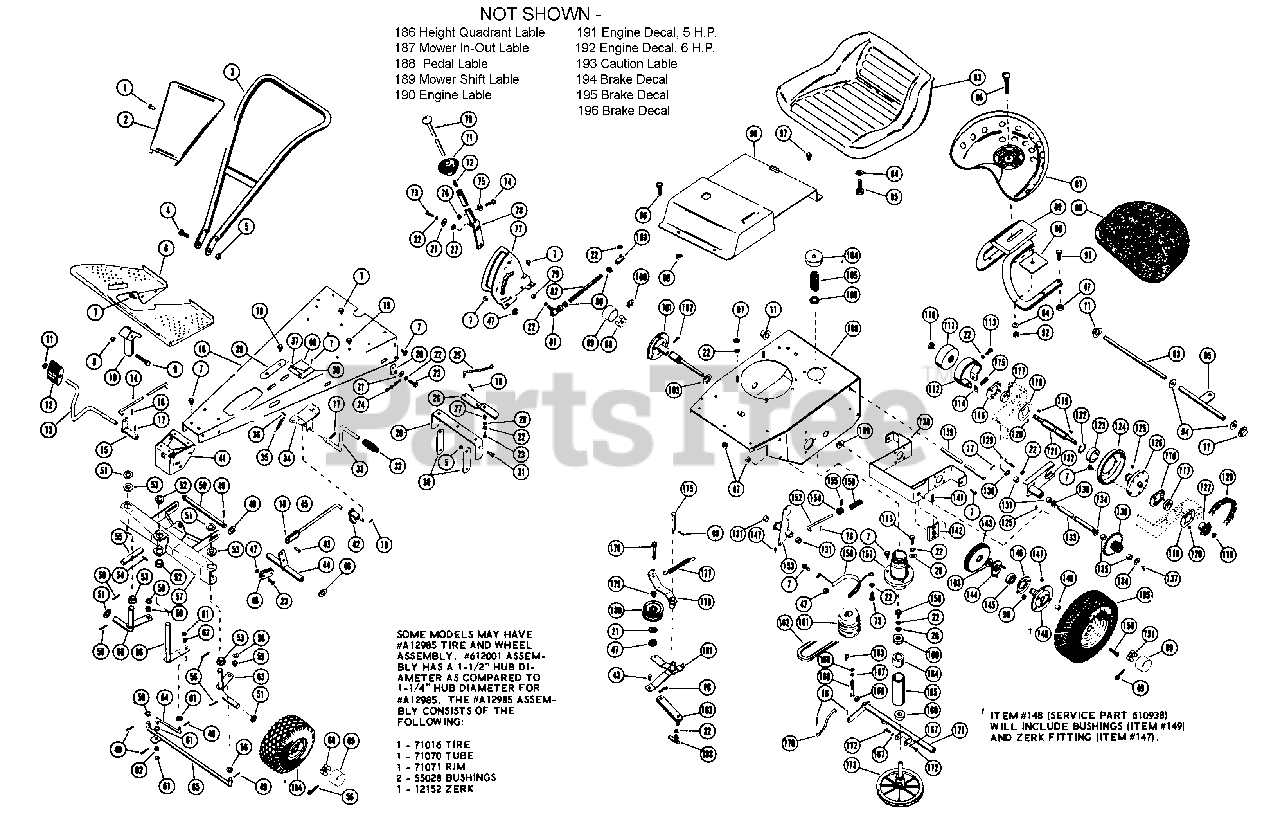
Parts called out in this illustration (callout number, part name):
1	RVT-POP.125 X .294 DOME
3	HANDLE BAR
4	BLT-HEX .38-16X2.50 PL GR2
5	NUT-LK-CTR .375-16 GR A PL
6	FOOT REST
7	BLT-SERHFWH .31-18X.50 PL
8	NUT-LK-CTR .250-20 PL
9	BLT-HEX .25-20X1.50
10	STEER BLOCK
11	CAP, .50 ROD YWZC
14	FRONT CLTCH ROD
16	PIN-COTR .09X.75 PL
17	PIN-ROLL .188X1.00
18	FRAME CHANNEL
19	BLT-SCRHFWH .38-16X.50 PL
20	BLADE BRAKE
21	WSHR-FL-STL .38X.875X.083 PL
22	WSHR-LK .312X.097 PL HVY
23	BLT-HEX .31-18X.75 PL GR2
24	BRAKE RELEASE CHAIN
26	CLTCH TRANSFER LEVER
27	SPACER BUSHING .5 X .32 X .21
28	WSHR-FL-STL 1.062X2.500X.165YZ
29	HANGER BRACKET
30	HANGER LINK
31	SHOULDER BOLT
33	MOWER CLTCH PEDAL
34	MOWER CLUTCH BRACKET
35	SG-TENS ??X.25X1.31 WLD 12 `
36	PIN-GRV .188X.75 TP G
38	THROTTLE CONTROL
39	GUIDE PLATE
40	BRAND PLATES
41	FRONT FRAME ASSM
42	MOWER OVERCENTER LEVER
43	CLEVIS PIN
44	MOWER CLUTCH LEVER
45	MOWER CLTCH LINK
46	WSHR-FL-STL .531X1.062X.095 PL
47	NUT-LK .312-18 GR A PL
48	FRONT LINK
49	PIN-COTR .12X1.0 PL
50	HANGER PIN
51	WSHR-FL-STL .755X1.375X.062 PL
52	BSHG-FLG.750X1X.375X1.250 IC
53	FLANGE BUSHING
54	PIN-ROLL .250X1.25
55	AXLE PIVOT PIN
56	PIN-COTR .12 X 1.25 PL
57	FRONT AXLE ASSM
58	WSHR-FL-STL .505X.875X.024 PL
59	BSHG-FLG.500X.625X.312X.750NY
60	R H WHEEL SPINDLE
61	WSHR-FL-STL .382X.812X.023 PL
62	BSHG-FLG .372X.500X.312X.625NY
63	L H WHEEL SPINDLE
64	STEERING LINK
65	TIE ROD
66	CENTER STEER COL
68	SPINDLE CUP
69	HUB CAP
70	SHIFT RELEASE HANDLE
71	SHIFT BALL
72	SG-COMP ??X.44X?? WLD 10
73	BLT-HEX .31-18X1.00 PL GR 2
74	BLT-HEX .25-20X1.25
75	WSHR-FL-STL .281X1.250X.048PL
76	NUT-LK TOP .250-20 PL
77	SHIFT CNTL
78	SHIFT LEVER
79	NUT-HEX .312-18
80	NUT-HEX .312-24 PL
81	SNAP IN BALL JOINT
82	SHIFT LINK
83	SEAT
84	WSHR-LK .500X.151 HVY PL
85	BLT-HEX .50-13X1.25 PL GR2
86	BLT-RDHDSQNK .50-13X1.25 PL
87	SEAT
88	SEAT COVER
89	SEAT BRACKET
90	SEAT SUPPORT WASHER
91	BLT-HEX .31-18X1.50 PL GR2
92	NUT .50-13 PL
93	HITCH SHAFT
94	WAVE WASHER .531X.781X.125FH
96	SCR-MCH .25-20X.63 CRPH PL
97	BLT-SERHFWH .31-18X.62 PL
98	DASH PANEL
99	NUT-LK-FLG .250-20 PL
100	PUSHNUT
101	R H AXLE
102	PIN-ROLL .188X1.25
103	WSHR-FL-STL .880X1.380X.062
105	SG-COMP .148X1.23X2.53 WLD87
106	SPRING RETAINER
108	REAR FRAME
109	FLANGE BUSHING
110	NUT-LK-CTR .50-20 PL
111	BRAKE DRUM
112	BRAKE BAND
113	BLT-HEX .31-18X.50 PL GR2
114	BRAKE BAND WASHER
115	SG-COMP .067X.562X1.75 WLD.34
116	BEARING FLANGE
117	BRG-BALL .500X1.38X.437
118	BEARING FLANGE
119	KEY-WDRF .125X.625X.250 SAE5
120	NUT-KEPS 10-24 PL
121	HEX SHAFT
122	RG-RTNG-EXT 1.250X.050
123	BRG-BALL 1.25X2.18X.63
124	FRICTION DISC
125	ZERK FITTING
127	9 TOOTH SPROCKET
128	CHAIN
129	BLT-HEX .31-24X.50 GR5
130	SEAL .625X.875X.125
131	BSHG-SLV .625X.750X.500 BR
132	SLIDING FORK
133	CARRIER SHAFT
134	WSHR-FL-STL .630X1.005X.062 PL
135	BRG-NEEDLE .625X.812X.50
136	PINION & SPROCKET
137	HYDRAULIC DRIVE FITTING
138	CARRIER
139	DISC FORK ROD
141	PIN-ROLL .188X1.50
142	LOCATING PLATE
143	DIFFERENTIAL ASSEMBLY
144	BEARING FLANGE
145	BRG-BALL .876 X 1.750 X .50
146	BEARING FLANGE
147	HYDRAULIC DRIVE FITTING
148	L H AXLE ASSEMBLY
149	BSHG-SLV .562X.625X.625 BRZ
150	BLT-WHL .50-20X.50 GR5 PL
151	SPINDLE CUP
152	BRAKE ROD
153	BRAKE BELL CRANK
154	SET COLLAR
155	SCR-SET .25-20X.50 SQHCUP HT
156	SG-COMP .1X.38X2.63 WLD 75
157	DRIVE SPRING HOUSING
158	REAR BELT FINGER
159	BLT-LK .31-18X.75 GR 5
160	BRG-BALL .625X1.375X.44
161	ENGINE SHEAVE
162	V-BELT, SAE 380-RAW EDGE
163	KEY-WDRF .156X.625X.25 SAE 6
164	BEARING SPACER .87 X .63 X 1.2
165	DRIVE SPINDLE HOUSING
166	WSHR-FL-STL .438X1.125X.19
167	WSHR-LK .375X.115 HVY PL
168	BLT-HEX .38-24X1.25 BLKO GR5
169	FORK SPACER
172	SCREW PIN
173	DRIVE DISK ASSEMBLY
175	PIN-CLEVIS .500 X 3.250
176	BLT-HEX .31-18X1.25 PL GR2
177	SG-TENS .063X.44X2.81 WLD 18
178	IDLER ARM
179	SPCR, BRG .315X.50X.688X.281
180	IDLER
181	SHIFT TRANSFER LEVER
182	SHIFT LINK
183	BALL JOINT
184	FRONT WHEEL ASSEMBLY
184	TIRE 4.10/3.50-4
184	WHL
184	BSHG-FLG .750X1.380X.750X1.557
184	ZERK FITTING
185	TIRE & WHEEL ASSEMBLY
185	WHL 6 IN O.D.
185	TIRE 6 X 4.10/3.50
186	HEIGHT QUADRANT LABEL
187	MOWER IN-OUT LABEL
188	PEDAL LABEL
189	MOWER SHIFT LABEL
190	ENGINE LABEL
191	5 H P ENGINE DECAL
192	6 H P ENGINE DECAL
193	CAUTION LABEL
194	BRAKE DECAL
195	BRAKE DECAL
196	CAUTION LABEL
